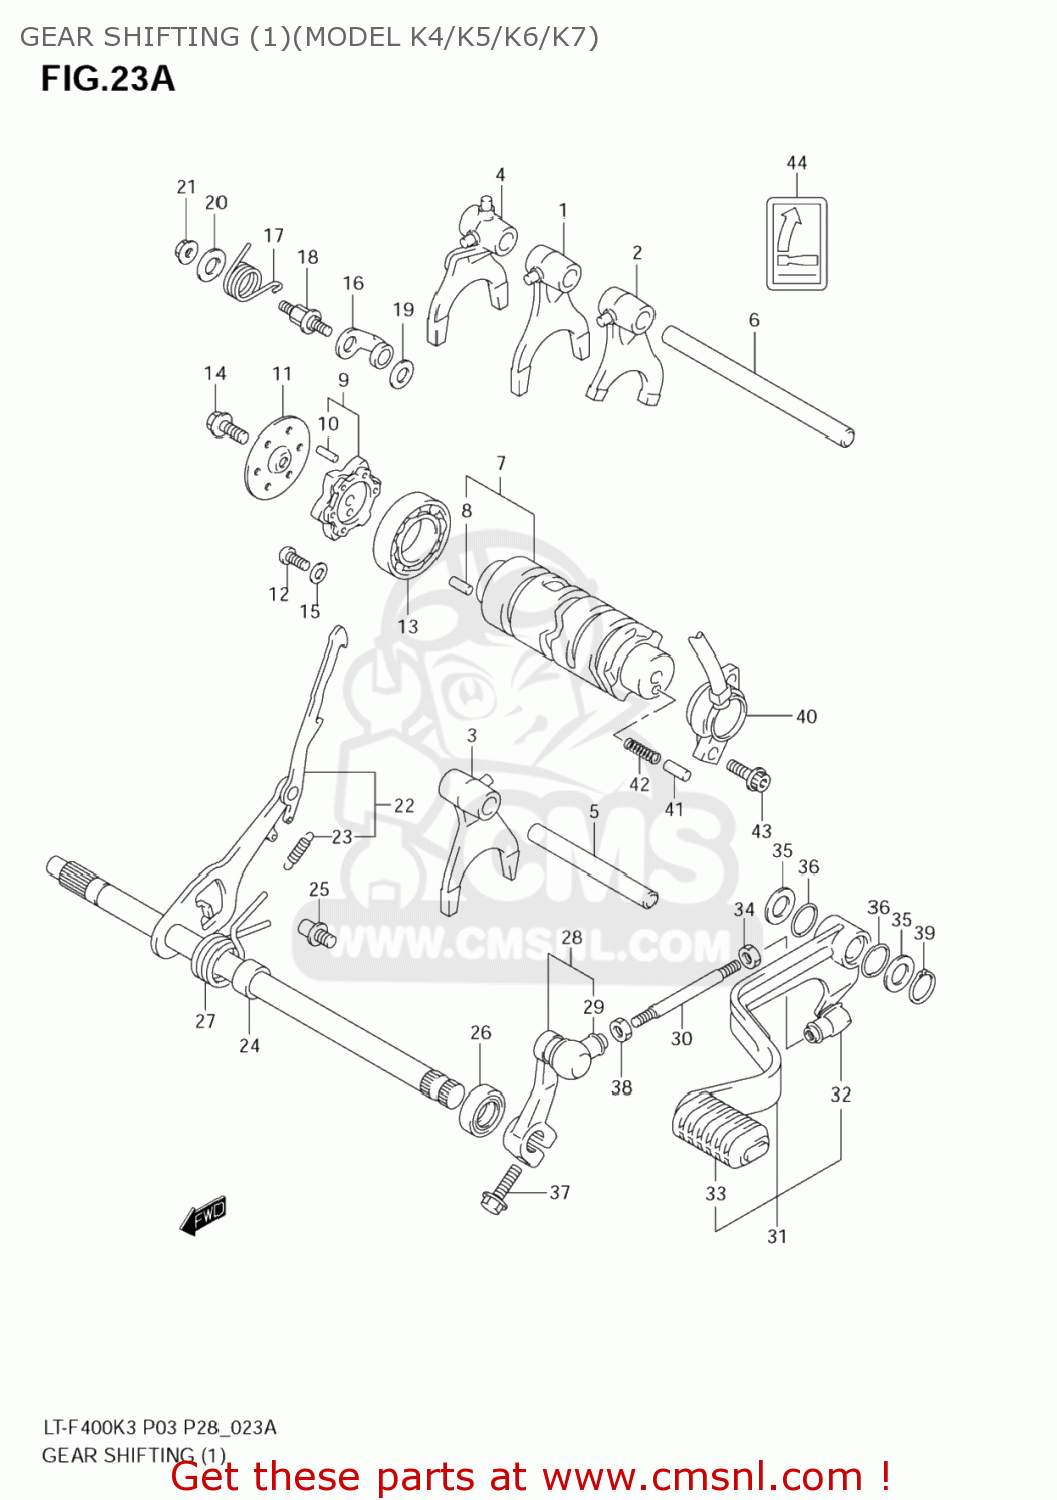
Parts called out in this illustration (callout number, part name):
1	FORK,GEAR SHIFT NO.1
2	FORK,GEAR SHIFT NO.2
3	FORK,GEAR SHIFT NO.3
4	FORK,GEAR SHIFT REVERSE
5	SHAFT,GEAR SHIFT FORK
6	SHAFT,GEAR SHIFT FORK
7	CAM,GEAR SHIFT
8	PIN
9	PLATE,GEAR SHIFT CAM
10	ROLLER(4X13.8)
11	GUIDE,GEAR SHIFT CAM PLATE PIN
12	BOLT(6X12)
13	BEARING(25X47X8)
14	BOLT
15	WASHER
16	STOPPER,GEAR SHIFT CAM
17	SPRING,GEAR SHIFT CAM STOPPER
18	SUPPORT,CAM STOPPER ARM
19	WASHER
20	WASHER
21	NUT
22	SHAFT,GEAR SHIFT
23	SPRING,GEAR SHIFT PAWL
24	SPACER,GEAR SHIFT SHAFT
25	STOPPER,GEAR SHIFT ARM
26	SEAL,OIL(14X22X6)
27	SPRING
28	ARM,GEAR SHIFT LINK
29	COVER,DUST
30	ROD,GEAR SHIFT LINK
31	LEVER ASSY,GEAR SHIFT
32	COVER,DUST
33	RUBBER,GEAR SHIFT PEDAL
34	NUT
35	SHIM(12X20X1)
36	O RING(D:2.2,ID:11.8)
37	BOLT
38	NUT
39	CIRCLIP,12 MM
40	BASE ASSY,NEUTRAL SW TERMINAL
41	PIN(5X15.5)
42	SPRING
43	BOLT
44	LABEL,GEAR SHIFT PATTERN
